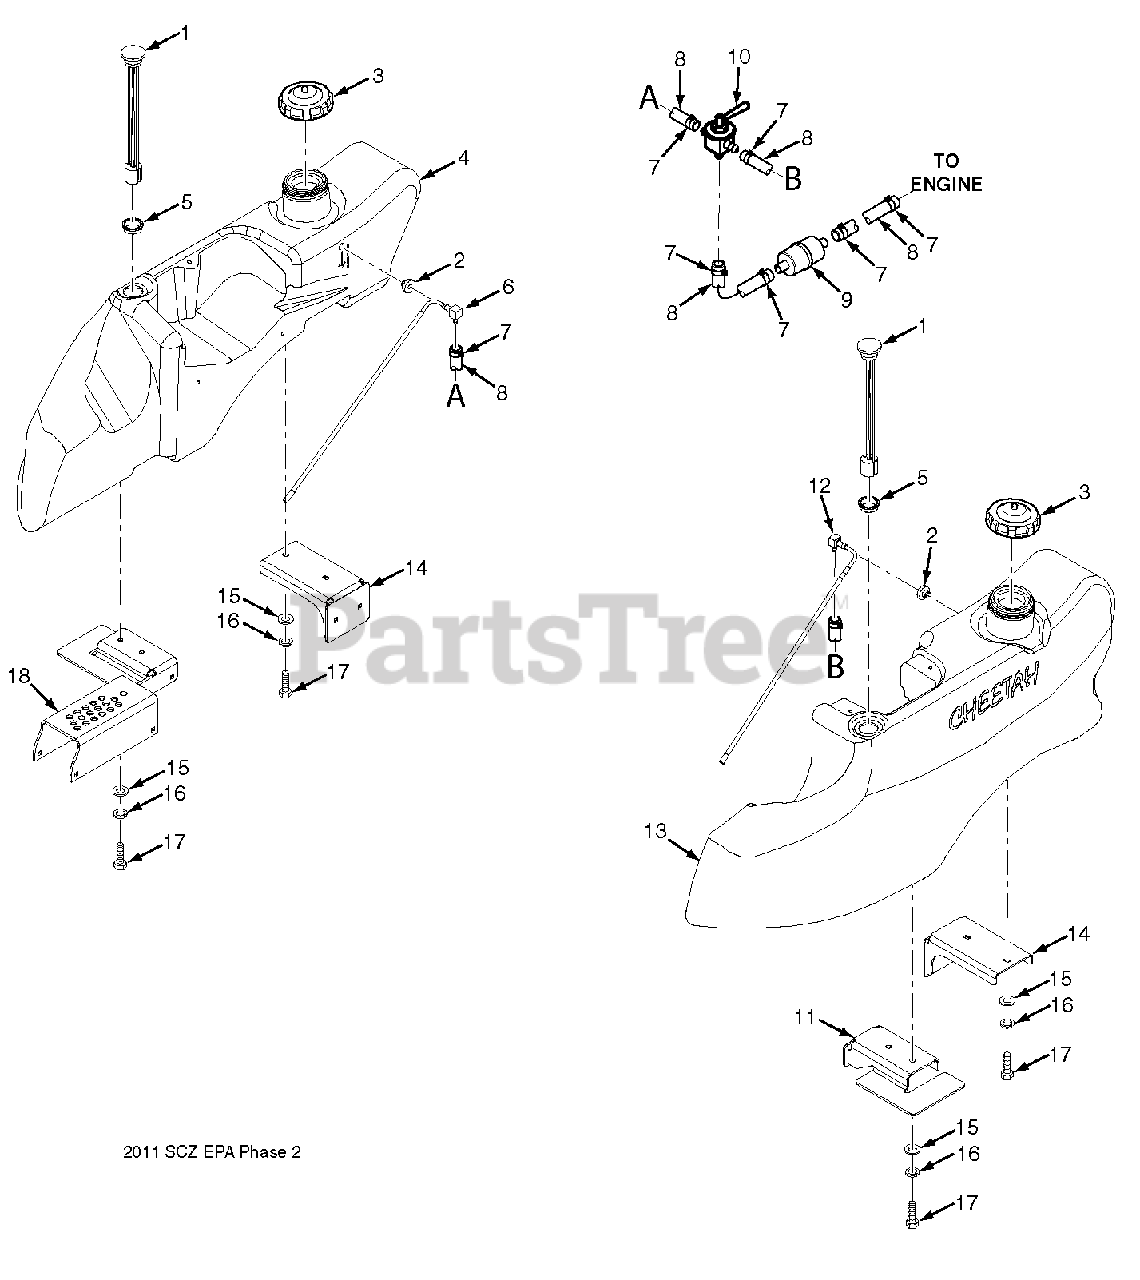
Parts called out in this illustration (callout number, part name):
1	Fuel Gauge
2	Bushing, .56 Dia. Viton
3	Cap, Fuel Tank
4	Fuel Tank Assembly, RH
5	Grommet
6	Fuel Tube Assembly, RH
7	Clamp, Fuel Hose 1/4" ID
8	Fuel Hose, 1/4" Non-Perm
9	Fuel Filter
10	Valve, Fuel Shut-Off
11	Mounting Bracket, Fuel Tank Front
12	Fuel Tube Assembly, LH
13	Fuel Tank Assembly, LH
14	Mounting Bracket, Fuel Tank Rear
15	Flatwasher, 5/16-.375 x .875 x .083
16	Lockwasher, 5/16" Spring
17	Bolt, Hex Head 5/16-18 x 3/4"
18	Adjustment Bracket, Upper Cut Height
